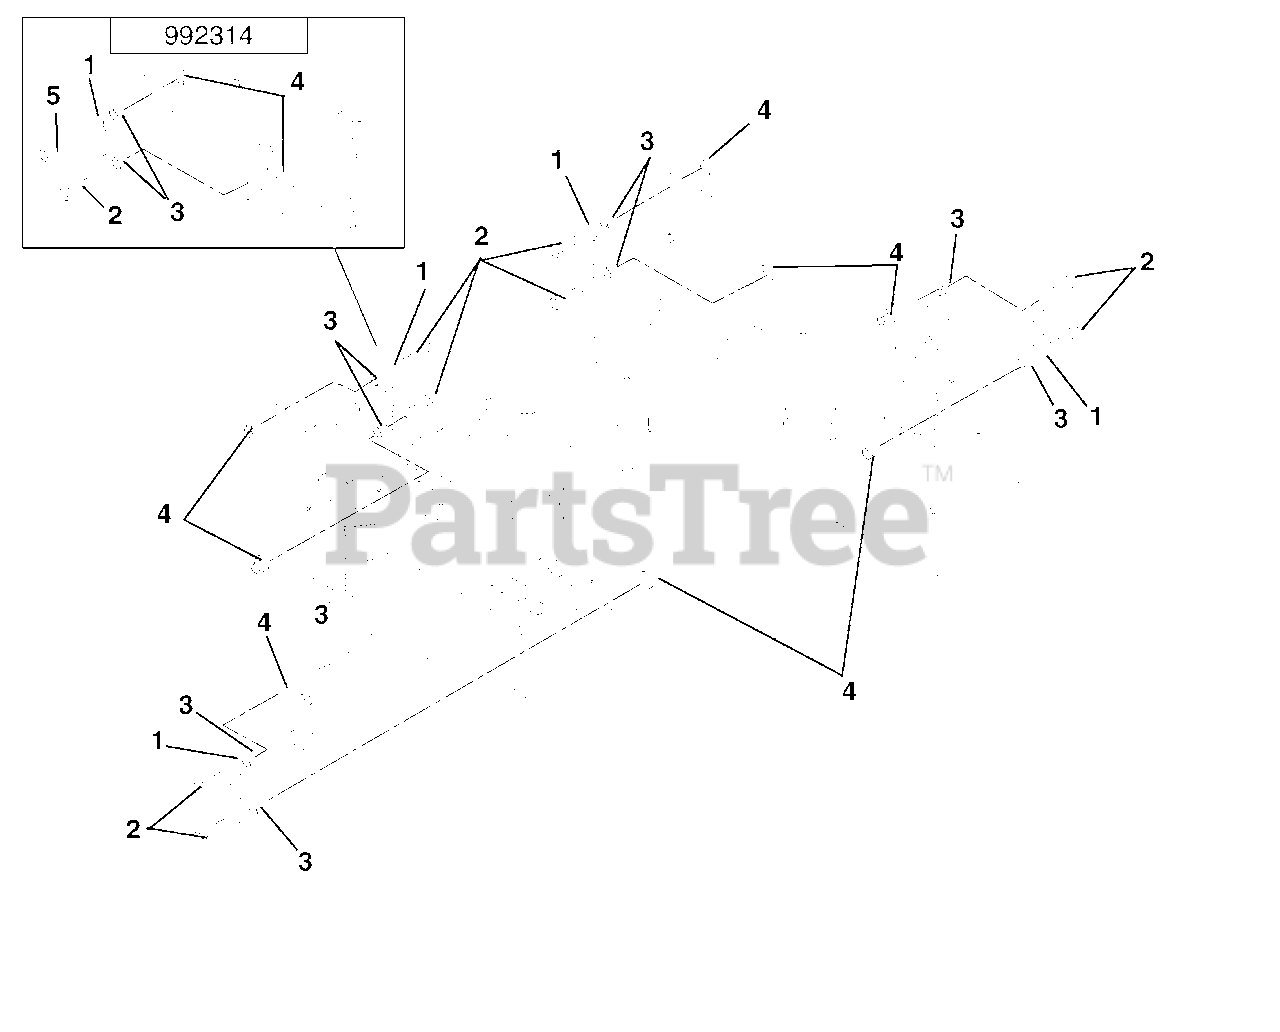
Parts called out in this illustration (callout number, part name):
1	Chain, Link
2	Bolt-Hex .50-13 x 2.00 Grade 5
3	Nut-Spin Lock-Flange .50-13
4	Nut-Locking-Top-Flange .50-13
5	Bolt-Hex .50-13 x 3.00 Grade 5
